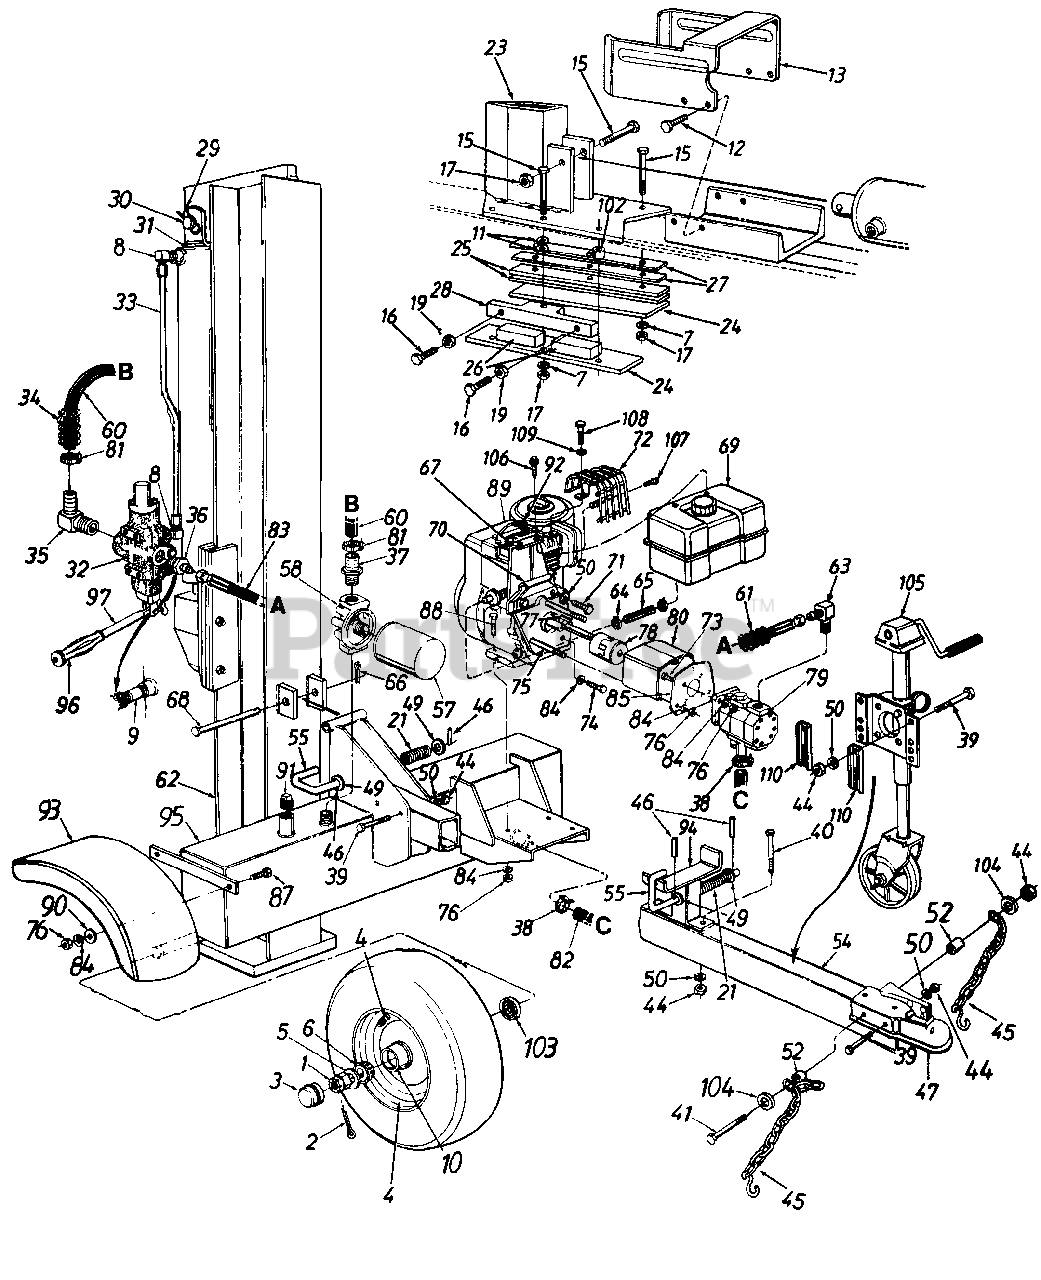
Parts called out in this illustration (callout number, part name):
1	Slotted Nut 3/4-16 Thd.
2	Cotter Pin 5/32" Dia.
3	Hub Cap
5	Fl-Wash .76" I.D. x 1.5" O.D.
6	Bearing Cone
7	L-Wash. 1/2" I.D.
8	90 Deg. Solid Male Adapter
9	Pipe Nipple 1/2 NPT
10	Bearing Cup
11	Fl-Wash .531" I.D. x .94" O.D.
12	Hex Cap Scr. 3/8-16 x 1" Lg.
15	Hex Bolt 1/2-20 x 2.75" Lg. (Grade 8)
16	Hex Bolt 3/8-24 x 1.5" Lg.
17	Hex L-Nut 1/2-20 Thd.
19	Hex Jam Nut 3/8-24 Thd. (Grade 5)
21	Comp. Spring 4" Lg.
29	External Cotter Pin
30	Cylinder Mounting Pin
33	Metal Pressure Tube
34	Hose Guard
35	Return Elbow
36	Adapter
37	3/4" Hose Barb.
38	Hose Clamp 1.5" O.D.
39	Hex Bolt 3/8-16 x 3" Lg. (Grade 8)
40	Hex Bolt 3/8-16 x 4.75" Lg.
41	Hex Bolt 3/8-16 x 4.25" Lg.
44	Hex Nut 3/8-16 Thd.
45	Chain - Tow Hitch
46	Roll Pin
47	Hitch Coupler
49	Fl-Wash .635" I.D. x .93" O.D.
50	L-Wash. 3/8" I.D.
52	Spacer .445" Lg.
57	Fllter Element
58	Fllter Head
60	Return Hose 3/4" I.D. x 44" Lg.
61	Hose Guard
64	Hose Clamp .37" Dia.
65	Fuel Line (6" Lg.)
66	Cotter Pin 1/8" Dia.
67	Tank Mtg. Brkt.
68	Hinge Pin 1/2 x 4.8" Lg.
69	Fuel Tank Ass'y.
70	Support Brkt.
71	Hex Bolt 3/8-16 x 1" Lg.
72	Muffler Guard
73	Hex Bolt 5/16-24 x 1" Lg.
74	Hex Bolt 5/16-24 x .62" Lg.
75	Hex Bolt 5/16-24 x 5.25" Lg.
76	Hex Nut 5/16-24 Thd.
77	Sq.-Key 1/4" x 2" Lg.
78	Flexible Coupling
79	Gear Pump
80	Coupling Shield
81	Hose Clamp 5/8"
82	Suction Hose 1" I.D.
83	High Pressure Hydraulic Hose 48"
84	L-Wash. 5/16" I.D.
87	Hex Bolt 5/16-24 x .75" Lg.
88	Hex Bolt 5/16-24 x 1.75" Lg.
89	Engine
90	Fl-Wash .344" I.D. x .875" O.D.
91	L-Vent Pipe Plug
92	Spark Plug Boot
97	Control Handle
102	Spacer 1/2" I.D. x .86" Lg.
103	Bearing Seal Only
104	Fl-Wash. 3/8" I.D. x .87" O.D.
105	Jack Stand
106	Hex AB-Tap Scr. 1/4 x 3/4" Lg.
107	Hex Wash. Hd. Scr. #8 x .5" Lg.
108	Hex Bolt 1/4-20 x .5" Lg.
109	Fl-Wash .25" I.D. x .5" O.D.
